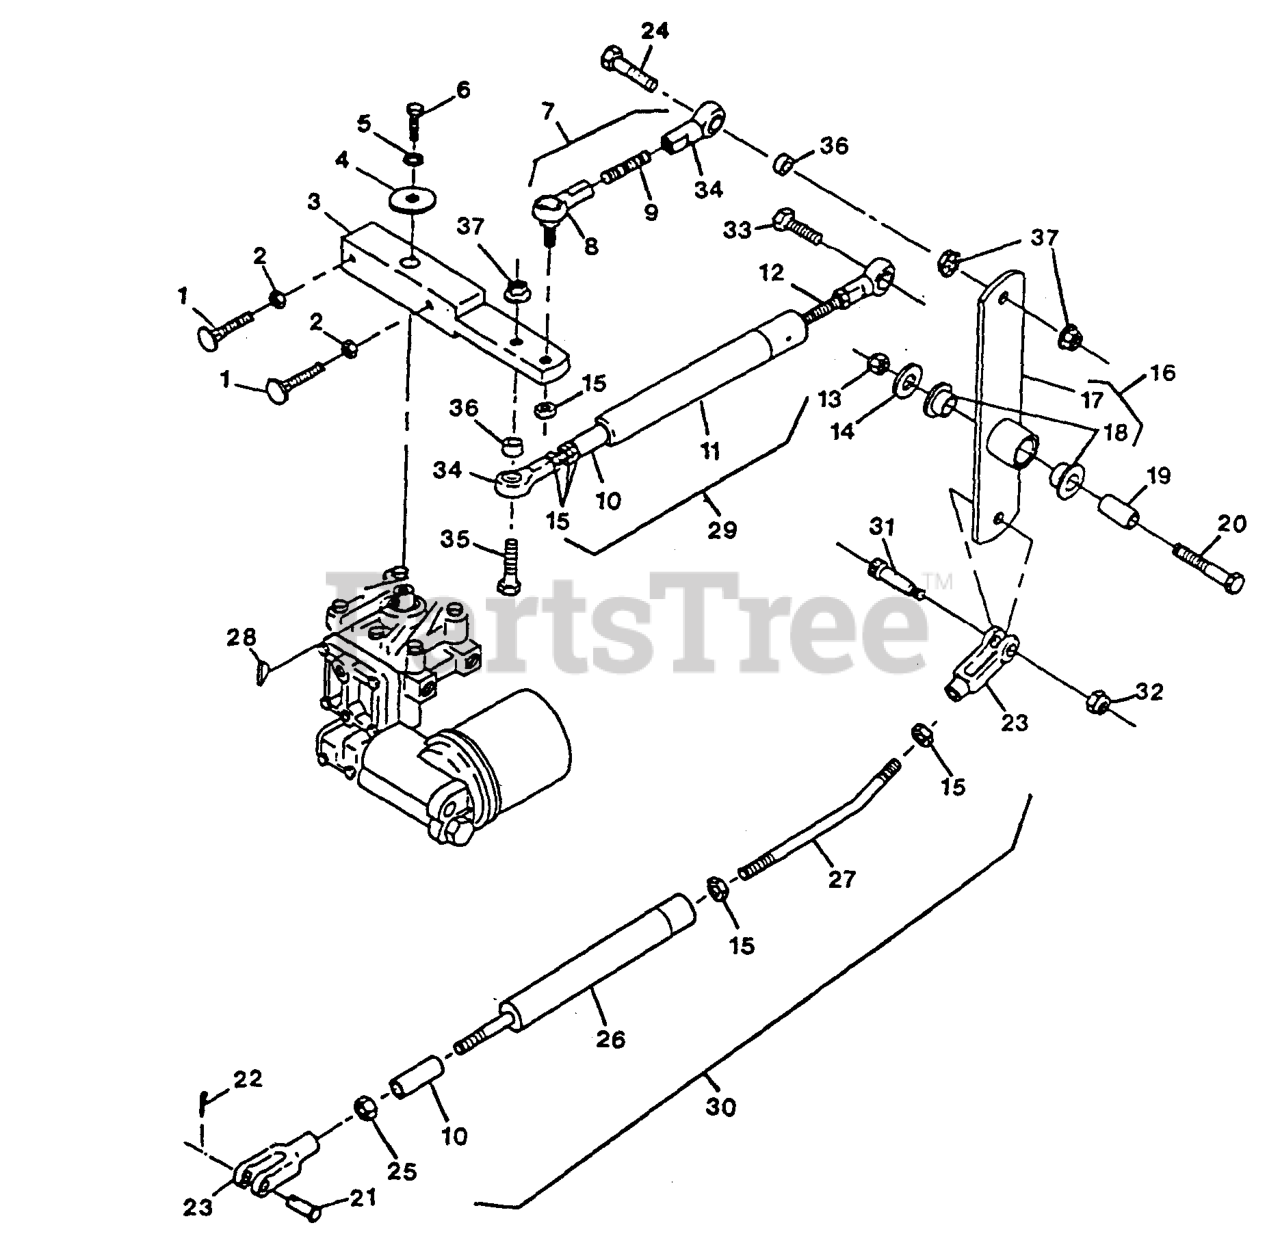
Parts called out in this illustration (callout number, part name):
3	WLD,ARM TRANSAXLT
4	WASHER-RETAINER, PULLEY
5	WASHER-LOCK
6	Capscrew, 1/4-20 X 1-1/2
8	BALLJOINT
9	ROD END PLTD.
10	BUSHING,SPRING GUIDE
12	ROD,END
17	WLD,IDLER LINKAGE
18	BEARING-CONTROL
19	BUSHING,MOTION LEVER
21	PIN-CLEVIS
23	YOKE-ADJUSTABLE
27	LINKAGE,ROD
30	ASM,PEDAL OVERRIDE
31	SCREW-HSH
34	BALLJOINT-RH
36	SPACER-PLATED
